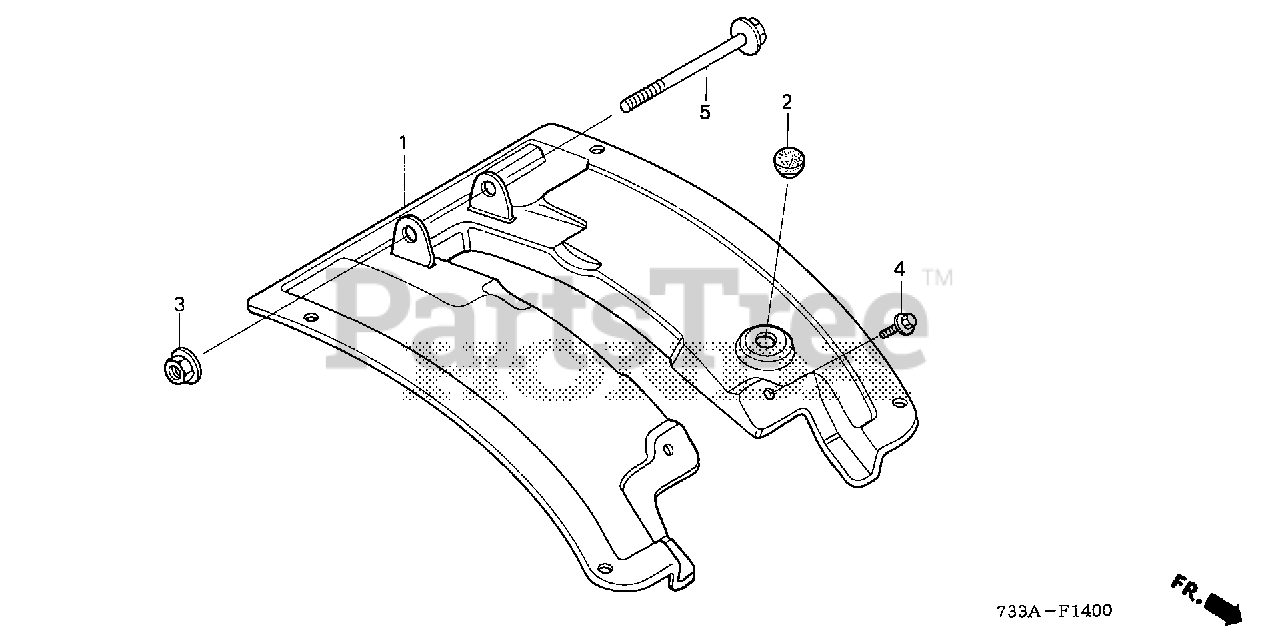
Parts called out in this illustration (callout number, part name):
1	FENDER, MAIN *R280* (POWER RED)
2	STOPPER, TENSIONER ARM
3	NUT, FLANGE (10MM)
4	BOLT, FLANGE (8X16)
5	BOLT, FLANGE (10X90)
